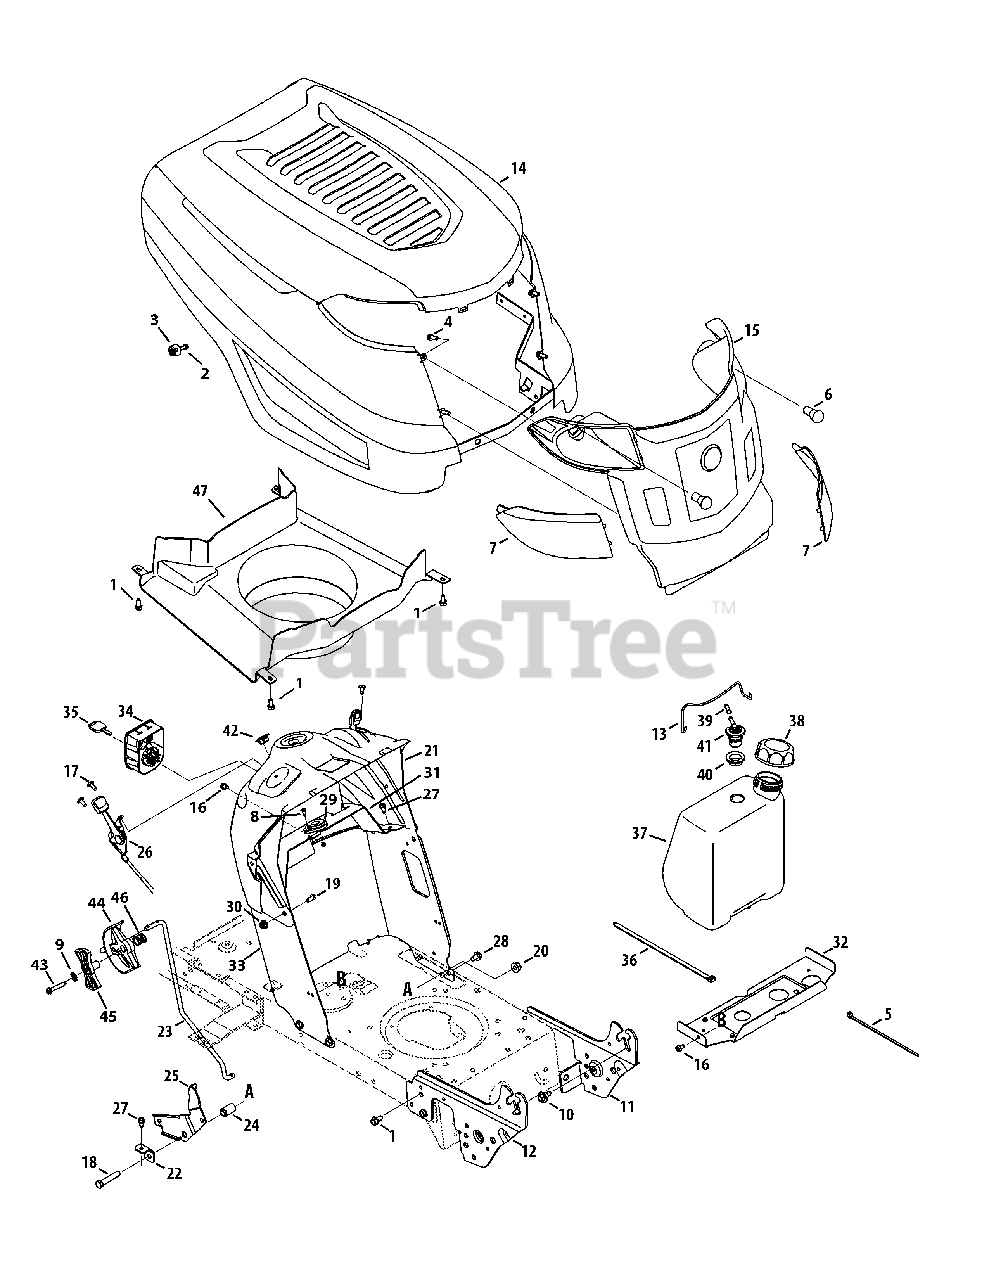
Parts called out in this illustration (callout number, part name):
1	Screw 5/16-18 x .750
2	Screw, #12-16 x 1.25
3	K-Style Bumper
4	Screw, 1/4 x .750
5	Cable Tie
6	Miniature lamp 12V socket
7	Grill Lens - LH
7	Grill Lens - RH
8	Screw, #10-16 x .500
9	Lock Washer, 1/4
10	Shoulder Screw .43 x .29
11	Suppport Bracket LH
12	Suppport Bracket RH
16	Screw, 1/4-20 x .500
17	Screw 1/4-20 x .500
18	Hex Screw 3/8-16 x 2.00
19	Hex Screw, 5/16-18 x .625
20	Flange Lock Nut 3/8-16
21	Dash, Upper
22	Speed Latch Tab
23	Speed Control Rod
24	Flange Spacer .39 x .671 x 1.095
25	Transmission Speed Latch
26	Throttle/Choke Control Cable
27	Tap Screw, 1/4-20, 0.625
28	Screw 5/16-18 x .625
29	Bearing, .628 ID x 1.36
30	Flange lock Nut 5/16-18
31	Bracket, Steering Support
32	Gas Tank Support Bracket
33	Dash, Lower NWNDW
34	Key Switch Module
35	Key, Assembly
36	Cable Tie
37	Fuel Tank, 1.36 Gallon
38	Fuel Cap
39	Hose Vent, 3/16
40	Rubber Grommet
41	Rollover Valve
42	Choke Plug
43	Hex Washer Screw, 1/4-20 x 1.50
44	Shift Lever
45	Index Control
46	Compr. Spring, .72 OD x .78
